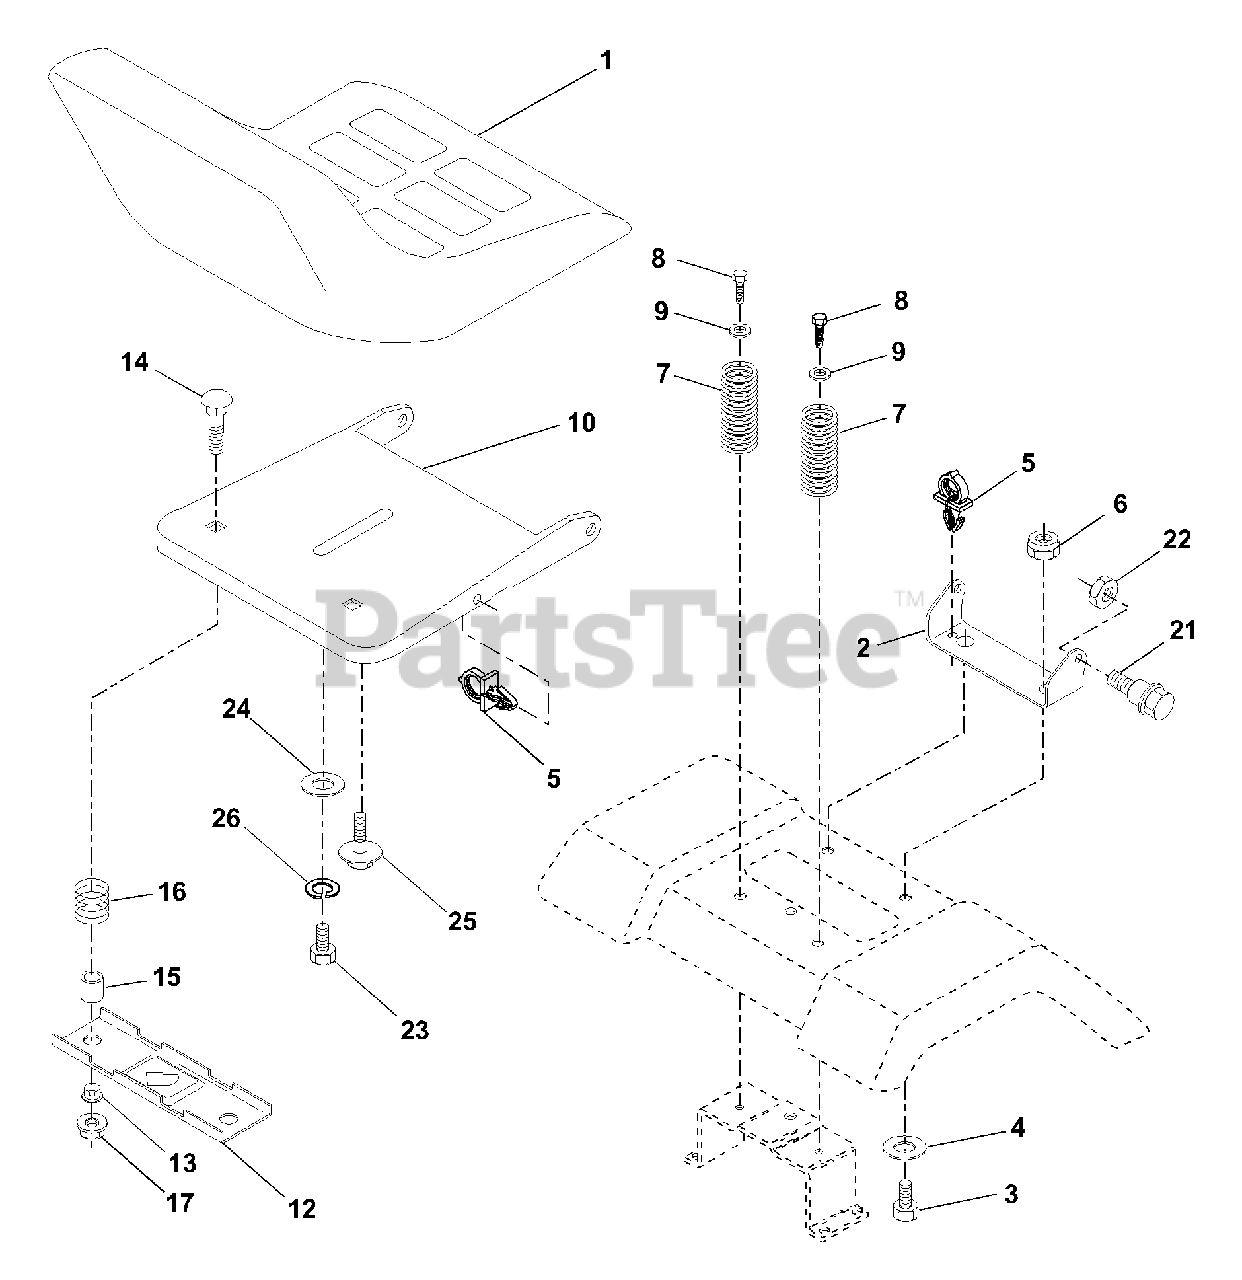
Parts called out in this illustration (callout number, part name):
2	Bracket Pvt St
3	Bolt Fin Hex 3/8-16unc X 1
4	Washer Flat 13/32 X 1X10 Ga
5	Clip Push-In Hinged
6	Nut Crownlock 3/8-16 UNC
7	Spring Seat Cprsn 2 250 Blk
8	Screw 3/8-16 X 1-1/2
9	Washer 13/32 X 1 X 14 Ga
10	Pan Seat
12	Bracket Mounting Switch
13	Bushing Snap Blk Nyl 50 Id
14	Bolt Rdhd Sht 1/4-20x1-1/2
15	Spacer Split 28x 96 Yel Zinc
16	Spring Cprsn 1 27 Blk Pnt
17	Nut Lock 1/4 Lge Flg Gr 5
21	Bolt Shld 5/16-18 Unc-2A
22	Nut Crown Lock Hex 5/16-18
23	Bolt Hex Black
24	Washer 17/32 X1-3/16X12 Ga
25	Bolt Shoulder
26	Washer Lock Hvy Hlcl 1/2
